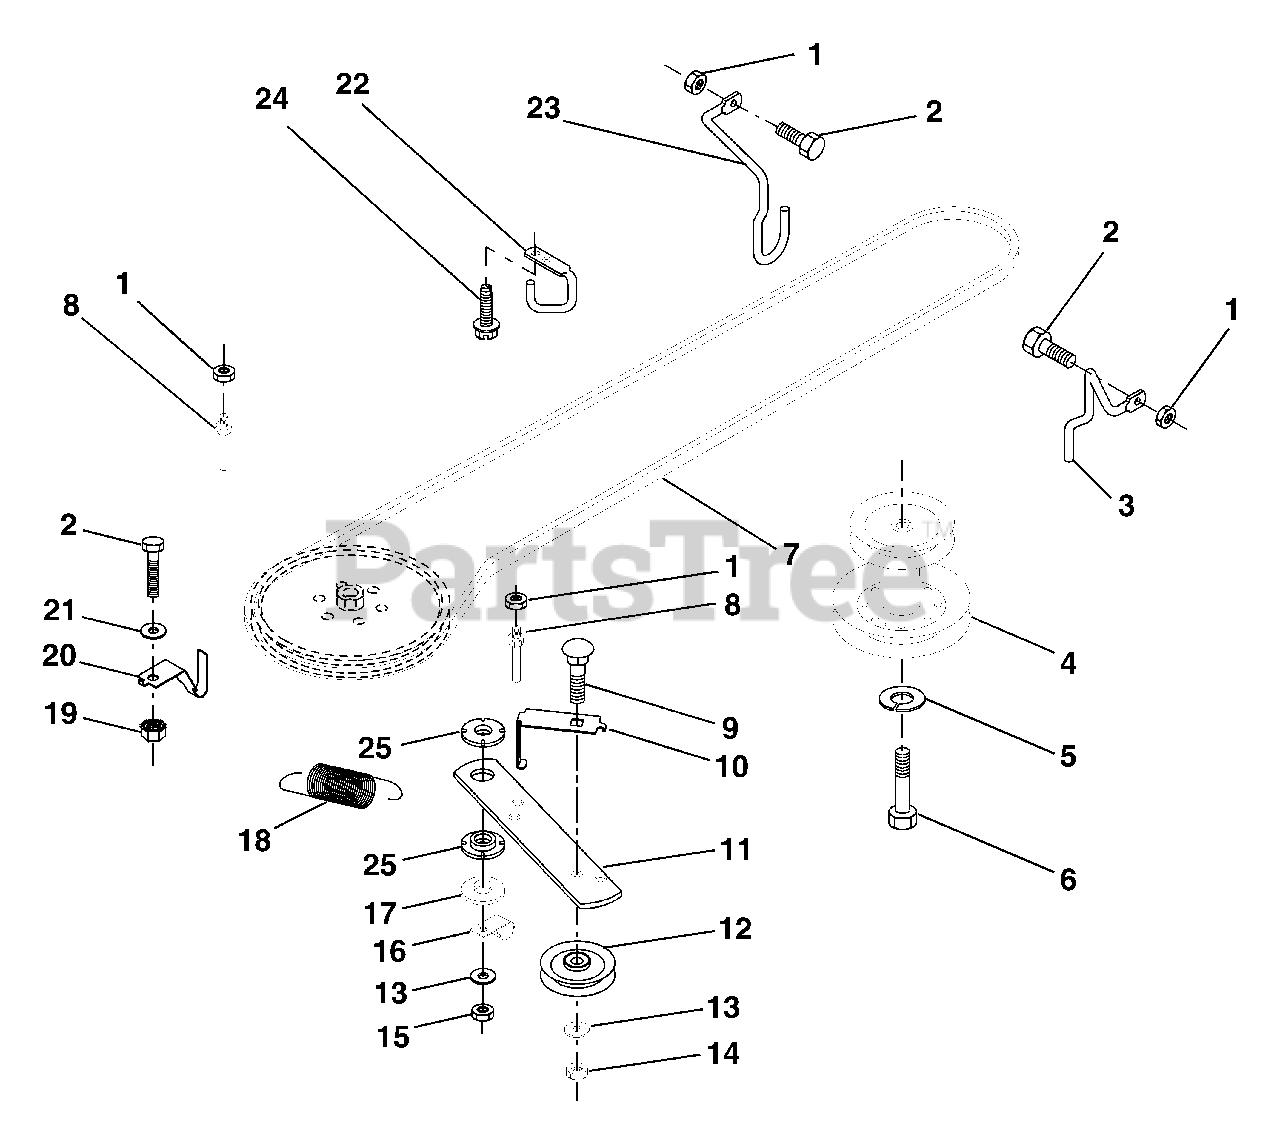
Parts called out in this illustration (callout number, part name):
1	Nut, Crownlock 5/16-18
2	Bolt, Hex Hd 5/16-18 UNC x 3/4
3	Keeper,Mower Drive, R.H.
4	Pulley, Engine
5	Washer, Lock 7/16
6	Bolt Hex 7/16-20 Gr. 5
7	Traction, V-Belt Drive
8	Keeper, T/A Ground Drive Belt
9	Bolt, Carr. 3/8-16 UNC x 1-1/2
10	Keeper, Belt Ground Drive Idler
11	Arm, Ground Drive Clutch
12	Idler, Flat
13	Washer 13/32 x 13/16 x 16 Ga.
14	Nut, Centerlock 3/8-16 UNC
15	Nut, Crownlock 3/8-16
16	Clip, Insulated
17	Spacer, Retainer
18	Spring Extension
19	Nut, Keps 5/16-18 UNC
20	Keeper, T/A Ground Drive Belt
21	Washer 11/32 x 5/8 x 16 Ga.
22	Keeper, Frame Ground Drive Belt
23	Keeper, Mower Drive, L. H.
24	Screw, Thd Cut 1/4-20 x 1/2
25	Bushing, Nylon
